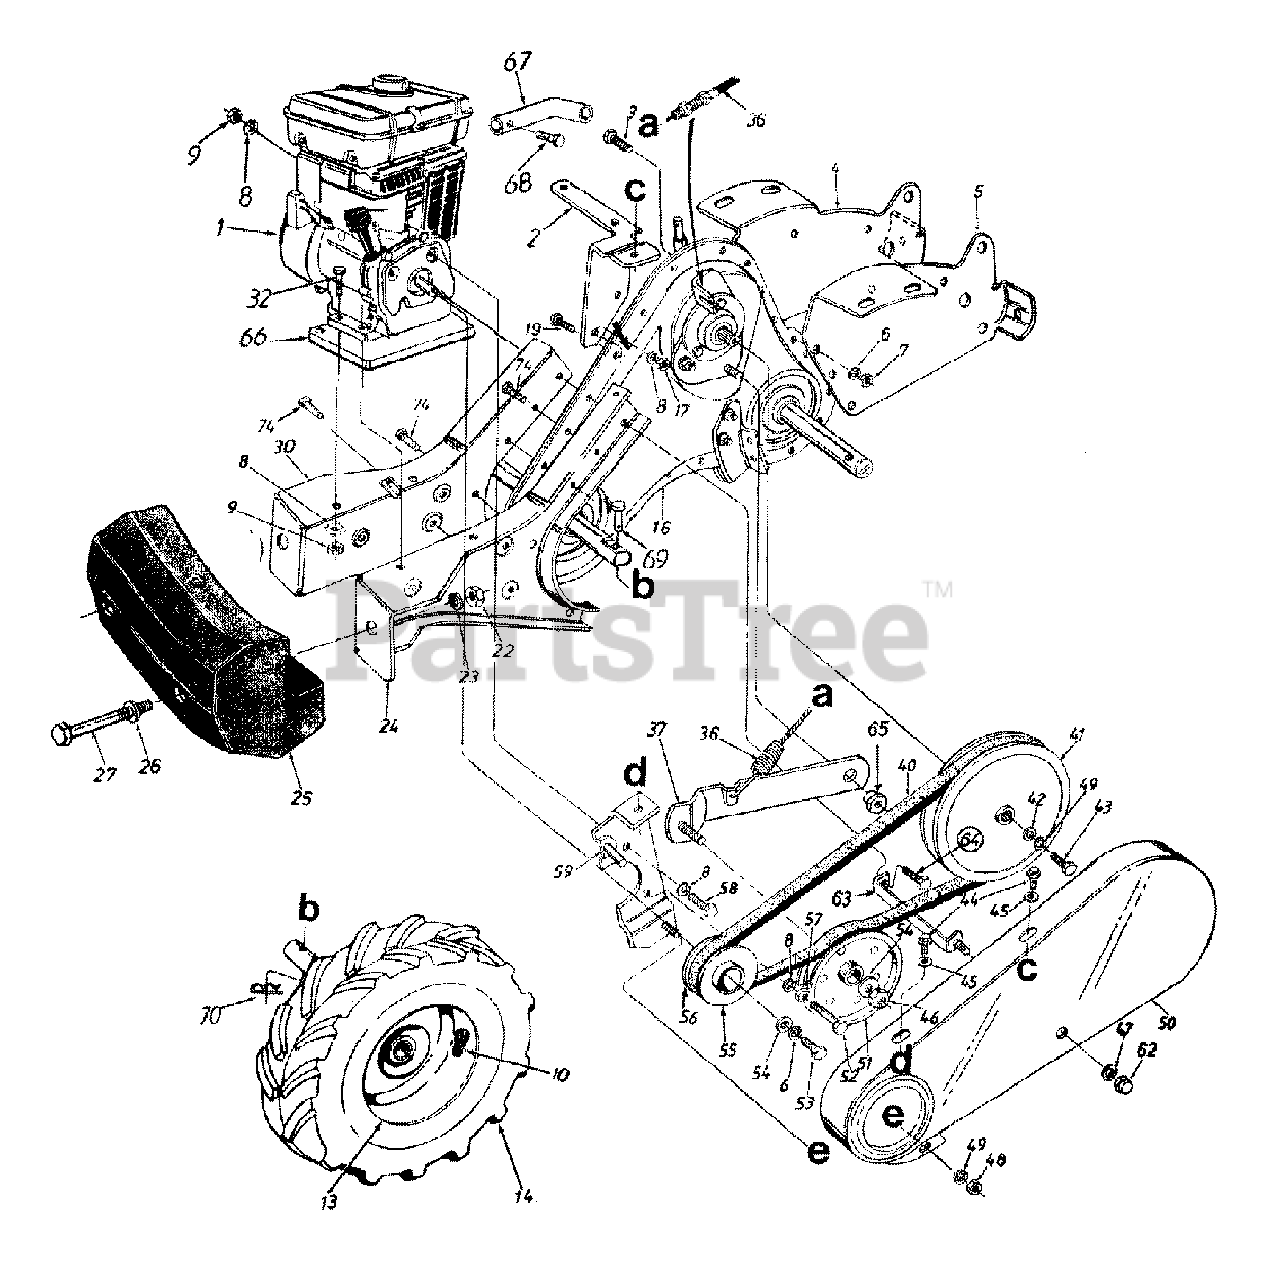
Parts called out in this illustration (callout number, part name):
1	Engine
4	Tine Shield Mtg. Brkt. - R.H.
7	Hex Nut 3/8-16 Thd.
8	L-Wash. 5/16" I.D.
9	Hex Nut 5/16-18" Thd.
10	Air Valve
16	Gear Case Ass'y. Comp.
17	Hex Nut 5/16-18 Thd.
19	Hex Bolt 5/16-18 x .75" Lg.
22	Hex Nut 1/2-13 Thd.
23	L-Wash. 1/2" I.D.
26	Fl-Wash. .510" I.D. x 1.0"
27	Hex Bolt 1/2-13 x 5.00" Lg.
32	Hex Bolt 5/16-18 x 2.75"
36	Clutch Control Cable 46" Lg.
37	Idler Bracket Ass'y.
40	V-Belt
41	Fl-Pulley 8" O.D.
42	Fl-Wash. 1/4" I.D. x .93" O.D.
43	Hex Bolt 1/4-28 x .75" Lg.
44	Hex Wash. Hd. S-Tap Scr. 1/4-20 x .50" Lg.
45	Fl-Wash. .281" I.D. x .625"
46	Hex Cent. L-Nut 3/8-24 Thd.
48	Hex Nut 1/4-20 Thd.
49	L-Wash. 1/4" I.D.
51	Fl-Idler w/Flanges 3.75" O.D.
52	Hex Bolt 5/16-24 x 1.75"
53	Hex Bolt 3/8-24 x 1.00" Lg.
54	Fl-Wash. 3/8" I.D. x 1.00"
55	Outer Engine Pulley Half
56	Inner Engine Pulley Half
57	Hex Nut 5/16-24 Thd.
58	Hex Bolt 5/16-24 x .62" Lg.
59	Belt Keeper Ass'y.
62	Hex Cap Nut 1/4-28 Thd.
63	Belt Cover Brkt. Ass'y.
64	Hex Bolt 5/16-18 x 1" Lg. (Gr. 5)
65	Shld. Nut
66	Engine Spacer Block
67	Outlet Pipe
68	Hex Wash. Hd. AB-Tap Scr. #8 x .5" Lg.
69	Clevis Pin
70	Hairpin Clip
74	Screw 5/16-18 x 1"
